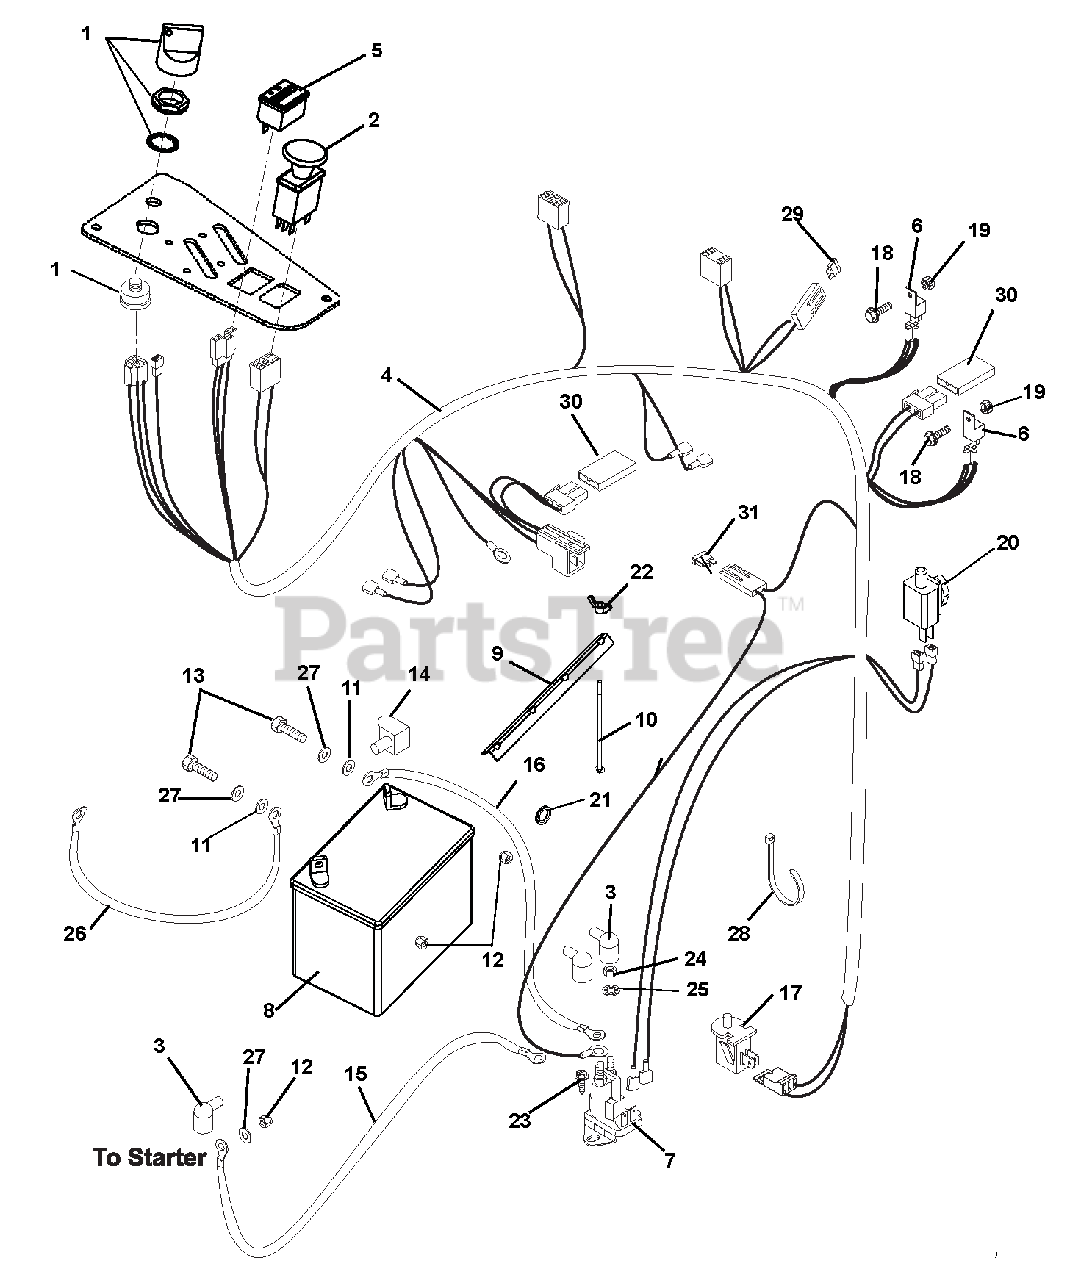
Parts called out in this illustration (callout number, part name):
1	SWITCH, IGNITION
2	HARNESS,CZ- -REMOTE SOL.
3	BOOT, EYELET TERMINAL
4	HARNESS - CZ REMOTE SOL.
5	HOUR METER - DIGITAL
6	RELAY,SEALED W/DIODE
7	SOLENOID, HP RTV
8	BATTERY, 300 CCA 10U1L
9	HOLD DOWN
10	BLT-RDHDSQNK .25-20X7.50 GR2YZ
11	@WSHR-FL-STL.281X.62X.065 YWZC
12	@NUT-HEX .25-20 YWZC
13	@BLT-HEX .25-20X.75 GR5 YWZC
14	INSULATOR
15	CABLE-POSITIVE BATTERY 9.00"
16	CABLE-NEGATIVE BATTERY 24.00"
17	SWITCH- SNAP MTG N.O.
18	@SCR-MCH 10-24X.50 HWH YWZC
19	@NUT-LK-NYL 10-24 W/INSRT YWZC
20	SWITCH, SINGLE POLE N.O.
21	GROMMET, 2.12" ID BUNA-N
22	NUT-LK WING .250-20 YWZC
23	@SCR-TAP .25-20X.50 HWH TR YWZ
24	NUT-JAM .31-24 YWZC
25	@WSHR-LK .31X.078 REG YWZC
26	CABLE, STARTER .31X23.00X.31
27	@WSHR-LK .25X.062 REG YWZC
28	CABLE TIE LG 5-1/2
29	FUSE 20AMP
30	DIODE, CONNECTOR SHELL
31	FUSE-25 AMP ATC TYPE
